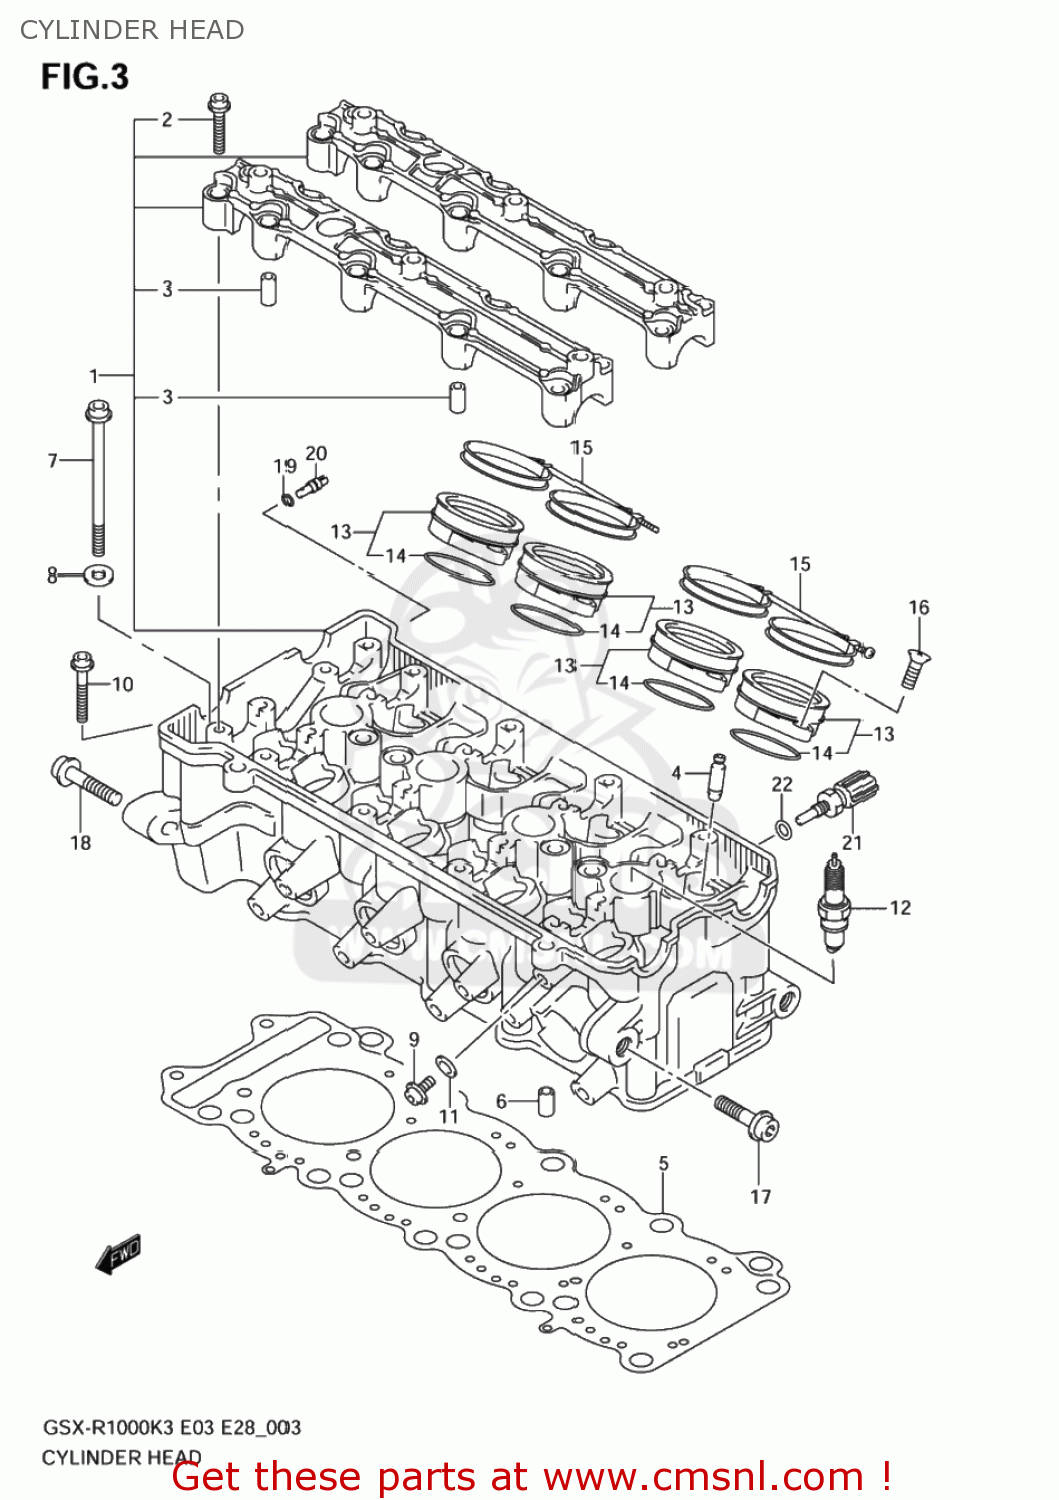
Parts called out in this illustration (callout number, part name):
1	HEAD ASSY,CYLINDER
2	BOLT
3	PIN(6.2X8X16)
4	GUIDE,VALVE
5	GASKET,CYLINDER HEAD (NAS)
6	PIN
7	BOLT(10X105)
8	WASHER(10.5X19X2)
9	BOLT(6X12)
10	BOLT,CYL.OIL P
11	GASKET(5.8X13X1.2) (NAS)
12	PLUG,SPARK(CR8E)
13	PIPE ASSY,INTAKE
14	O RING(D:2.4,ID:47X42)
15	CLAMP,INTAKE PIPE
16	SCREW ,6X16
17	BOLT(10X45)
18	BOLT(10X55)
19	O RING(D:1.2,ID:4)
20	JET(8)
21	SENSOR,WATER TEMP
22	GASKET(12X17X1) (NAS)
